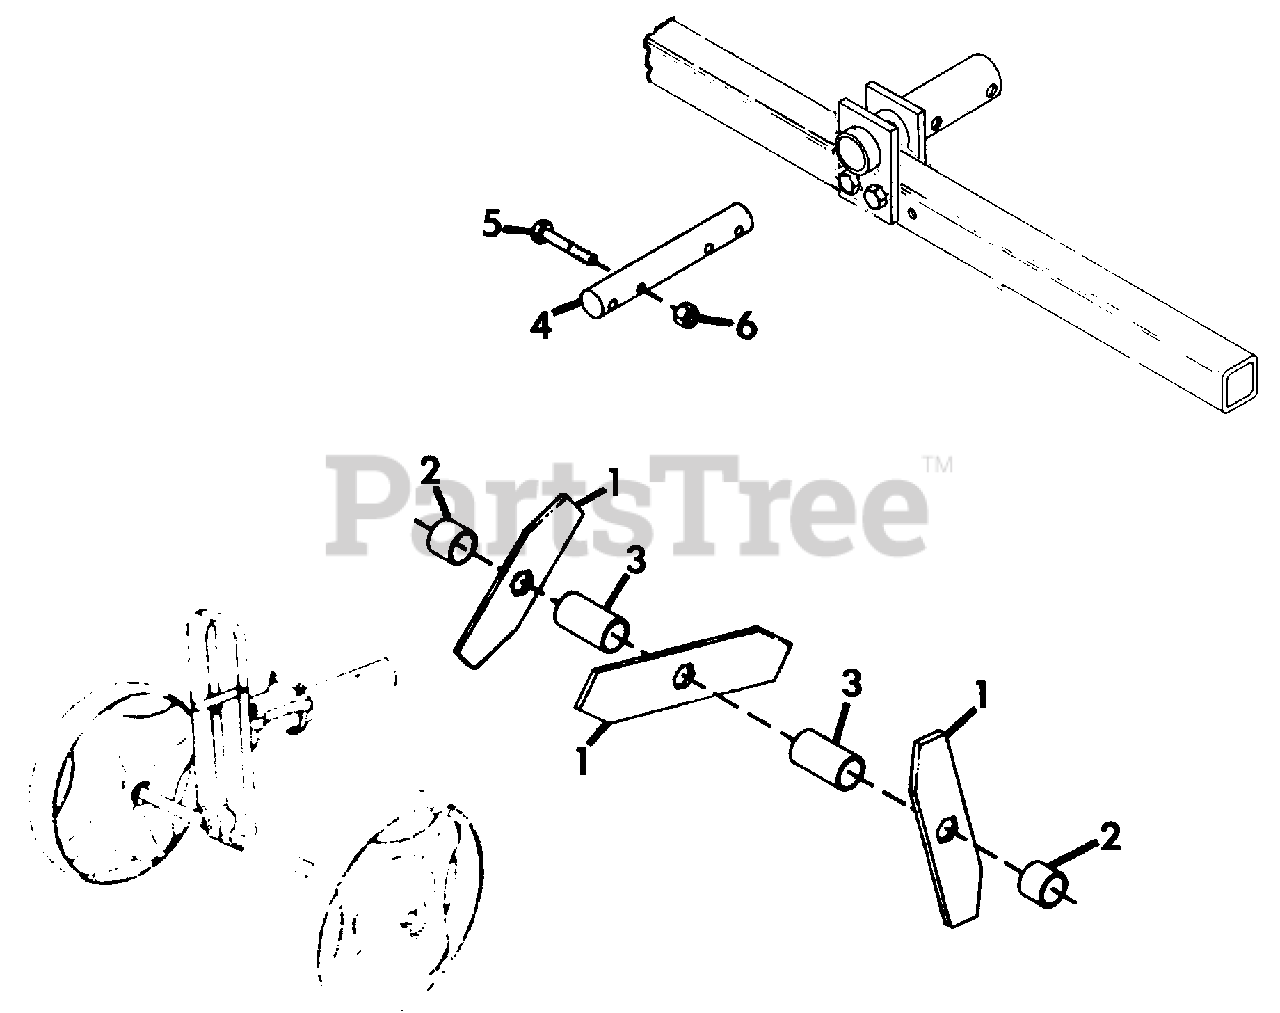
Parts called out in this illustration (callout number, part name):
1	TINE, CUTTER
2	SPACER, TINE
3	SPACER, TINE
4	BAR, EXTENSION
5	BOLT, HEX 1/2-13X2.75
6	NUT, LOCK 1/2-13
